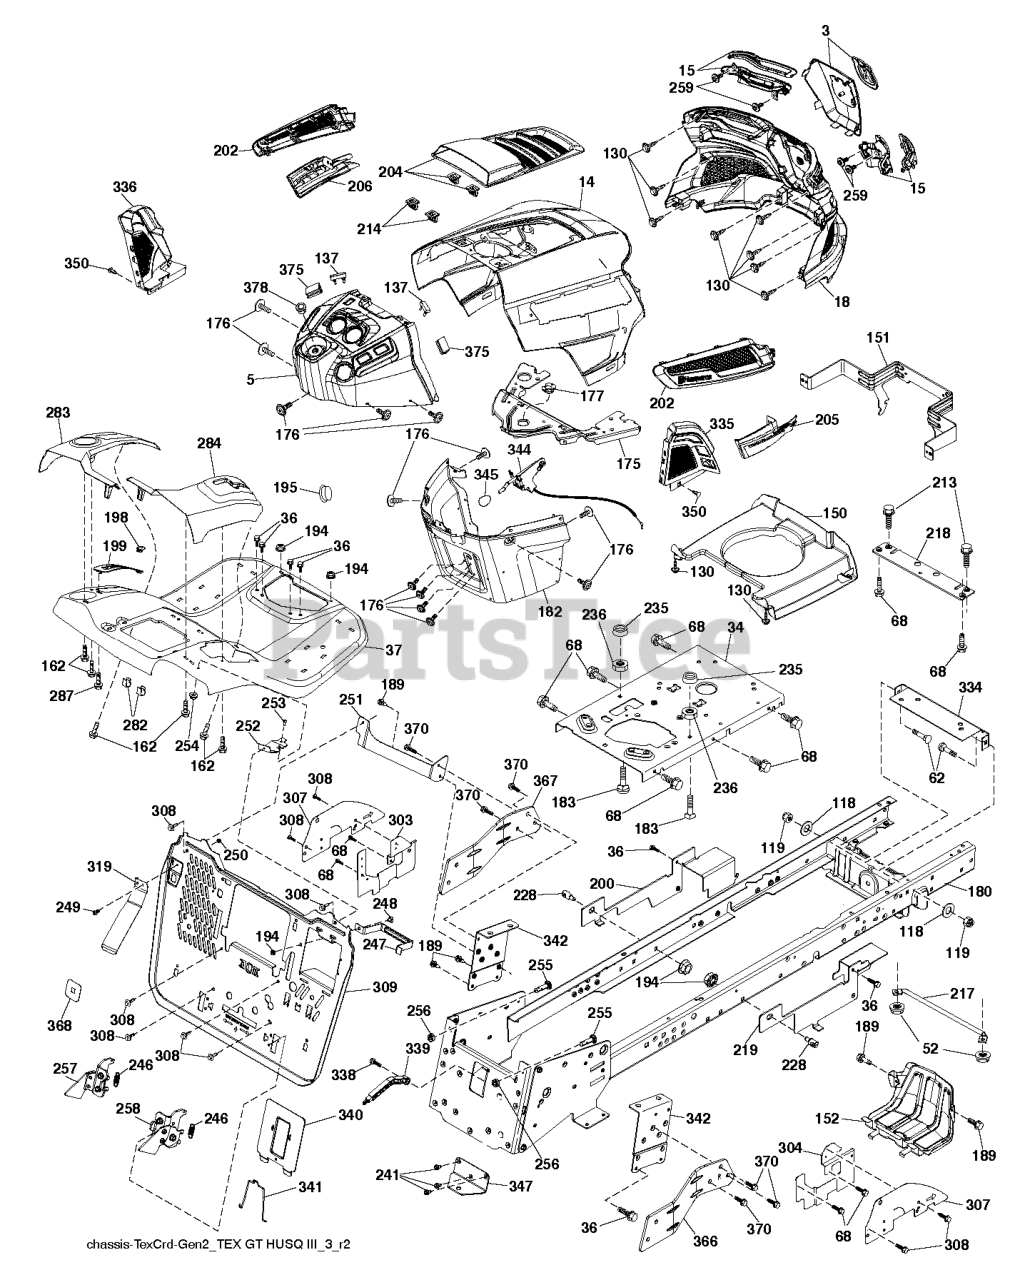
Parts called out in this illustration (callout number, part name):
5	DASH.UPR.GT2.DUAL.RD.PT
14	KIT.HOOD.ASM.HUSQ.GT.TEX.668
15	Service Kit
36	BOLT.5/16-18UNCX3/4 W/SEMS.BLK
37	FENDER.TEX.SRD.CRD.BASE
118	WASHER PLAIN WASHER 3/8 X 0.08
137	BUMPER DASH
150	AIR.DUCT.GTV.BLACK
151	SERVICE KIT PIVOT BRACKET BRAC
152	SHIELD.BROWNING.PNT.GT.V2
175	PLATE.PNT.CROSSMEMBER.HUSQ/PRE
176	SCREW.#10-24X5/8.RN.QU
177	BUSHING STEERING
180	CHASSIS WELDMENT.CRD2.BKP_BLTS
182	DASH.LOWER.COMMON.12V.ADAPTOR
189	BOLT.HEX.HD.WASHER.5/16-18X.75
195	PLUG.HOLE.DASH.LOWER.12V.BLK
198	INDICATOR.DECK.LIFT.RED
199	PLATE.DECKLIFT.SRD
200	SHIELD.LH.CHASSIS.MS431
202	Vents
205	SIDE.TRIM.RH.GT.HUSQ.II
206	SIDE.TRIM.LH.GT.HUSQ.II.GRAY
213	SCREW HEXAGON HEAD SCREW 5/16-
214	CLIP.RETAINER.TINNER.
217	ROD.PIVOT.HOOD
218	X-PIECE.HOOD.STOP.NON/
219	SHIELD.RH.CHASSIS.MS431
228	STUD.W/"D"ANTI-ROTATION
236	NUT.CENTERLOCK.5/16-
246	SPRING.LTCH.BGR.GEN2.5.CRD.TEX
247	STRAP.BATTERY.TCRD.GEN2.5X431
248	BOLT ROUND HEAD SQUARE NECK BO
249	SCREW.BUTTONHD.10-24X1/2.(2 2)
251	BRACKET.PNT.LH.SUPP.BKPLT.EDIP
252	BRACKET.PNT.RH.SUPP.BKPLT.EDIP
253	BOLT CUP HEAD SQUARE NECK BOLT
254	NUT HEX_LRG FLG_1_4-20_LOCK
257	LATCH.ASM.BGR.LH.GEN2.5.STMPD
258	LATCH.ASM.BGR.RH.GEN2.5.STMPD
282	CLIP.RETAINER.CONSOLE.LT.HUSQ
283	CONSOLE.DECKLIFT.CRDII.498
284	CONSOLE.PEDAL.HYDRO
287	SCREW 1/4X20
303	Shields
304	Shields
307	SHIELD.UPPER.CRD.SRD.ISO
308	BOLT.5/16-18UNCX3/4 W/SEMS.BLK
309	BACKPLATE.TEXCRD2.5.BAGGER.479
319	LEVER.PRSNC.BGR.TEX.CRD.GEN2.1
334	BRACKET.ENGINE.
335	COVER.LOWER.DASH.RH.BLACK
336	COVER-LH.LOWER.DASH.GT2.BLACK
339	SUBASM.BAGGER.FULL.LVER.(2 2)
340	BATTERY.DOOR.TCRD.GEN2.5.MS479
341	LATCH.BATTERY.DOOR.TCRD
342	SUPPORT.PNT.FENDER.CRD.TEX
344	CONTROL.EZ.MULCH.TEX/CRD
345	KNOB - SHIFT
347	HITCH.TOW.TEX.CRD.GEN.2
350	CLIP.X-MAS.TREE
366	Brackets
366	BRACKET.RH.FRONT.BAGGER.BLACK
367	BRACKET.LH.FRONT.BAGGER.BLACK
367	Brackets
368	FULL.LEVER.BAGGER.TEX.CRD
370	SCREW 3/8-16X1
375	BUMPER CLIP-ON. DASH 1"
378	BUSHING FLANGE; PLASTIC
